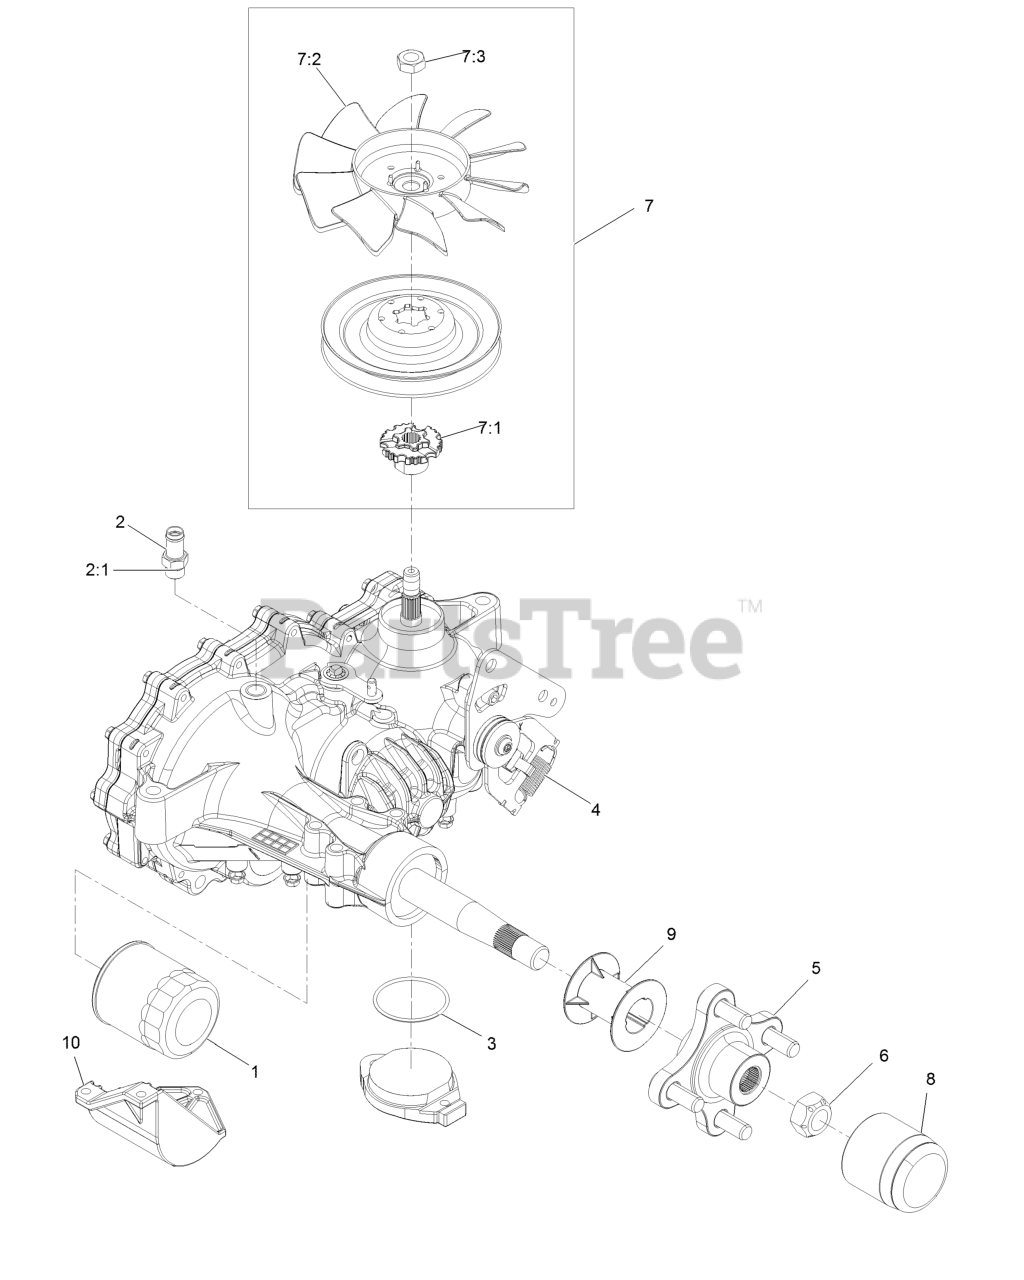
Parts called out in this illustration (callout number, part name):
1	Element-Oil Filter, HYD
2	Adapter-Straight
2:1	O-Ring
3	O Ring-Seal
4	Spring-Extension
5	Hub-Offset
6	Nut-Hub
7	Fan And Pulley Kit
7:1	Hub-Fan
8	Cap-Axle, Long
9	Tube-Axle
10	Guard-Filter, RH
11	Seal Kit
